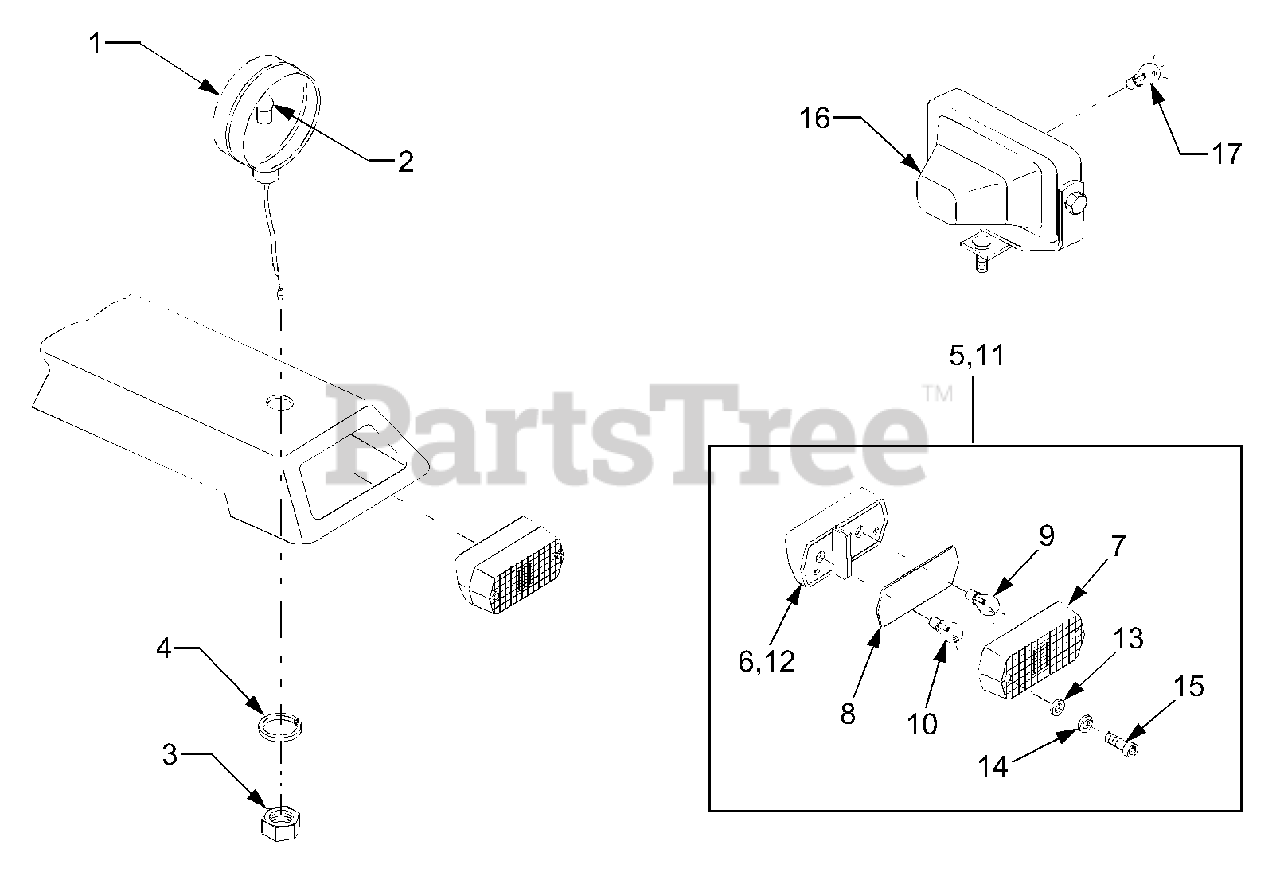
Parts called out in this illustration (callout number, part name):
1	Lamp, Hazard
4	Washer, Spring
5	Reflector Amp Ass'y (LH)
11	Reflector Amp Ass'y (RH)
13	Washer, Plain
14	Washer, Spring
16	Working Lamp Ass'y
